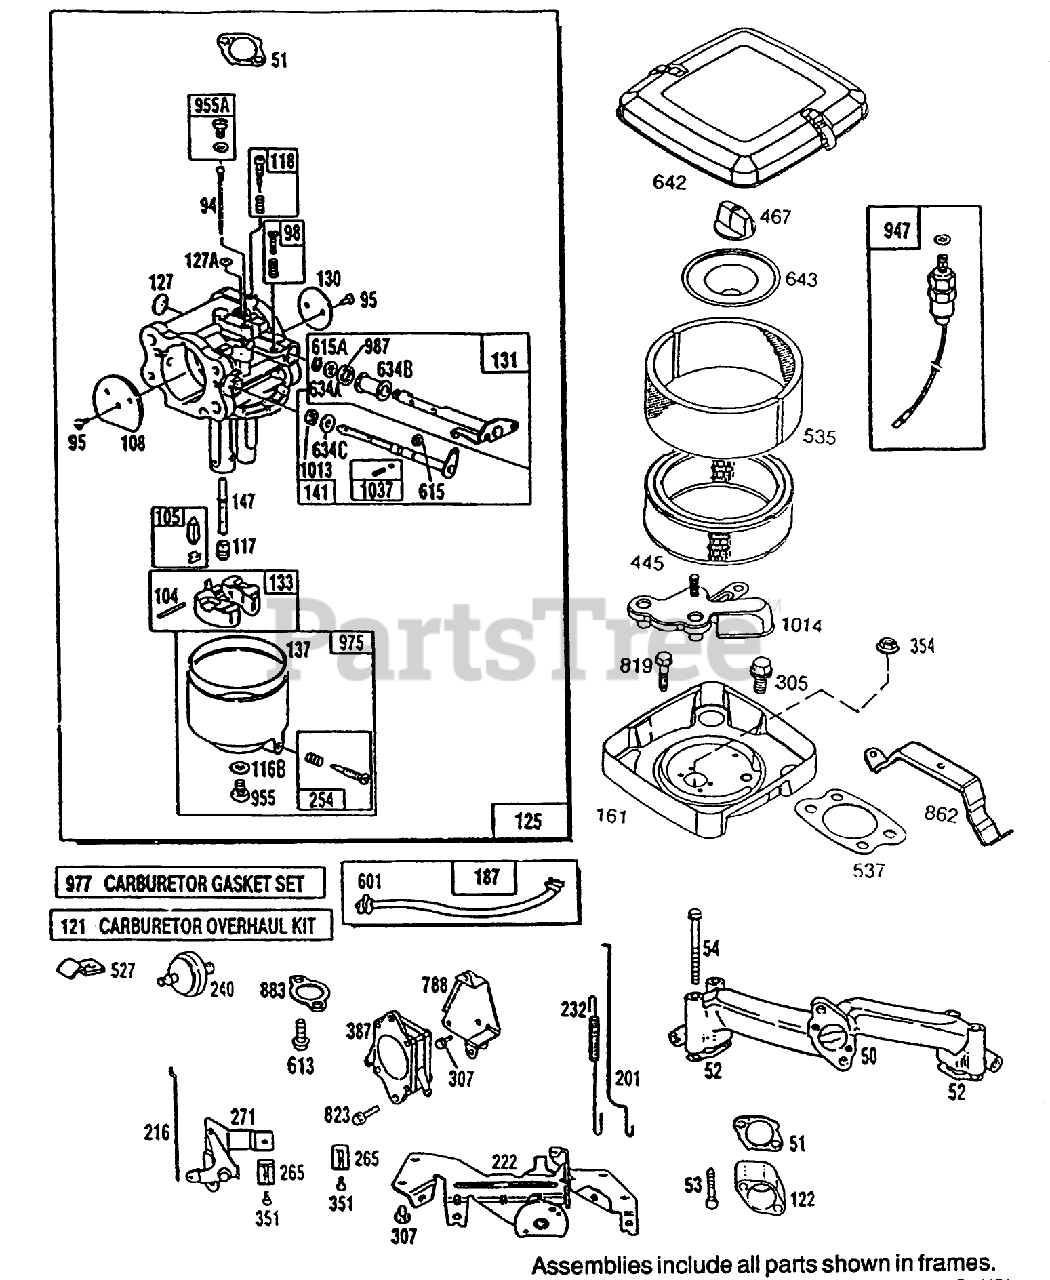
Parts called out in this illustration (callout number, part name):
50	BRIGGS-805409
51	BRIGGS-805149
52	Gasket-Intake Manifold
53	BRIGGS-805360
87	BRIGGS-805054
95	BRIGGS-805561
98	BRIGGS 807705
104	BRIGGS 805586
105	BRIGGS 807706
118	BRIGGS-807707
121	BRIGGS-807962
122	BRIGGS-805329
125	BRIGGS-808255
127	BRIGGS 805570
127A	BRIGGS 805571
131	BRIGGS-807709
133	BRIGGS-807710
137	BRIGGS-807716
141	BRIGGS-807711
147	NOZZLE
161	Base-Air Cleaner
201	BRIGGS 805480
216	BRIGGS-805439
222	BRIGGS-807610
254	BRIGGS-807713
305	BRIGGS 805406
307	BRIGGS-78-4310
351	BRIGGS 805169
445	CARTRIDGE-CLEANER, AIR
467	BRIGGS-491875
535	ELEMENT-FILTER
537	BRIGGS 805655
601	BRIGGS-93053
615	BRIGGS 805578
615A	BRIGGS 805577
634A	BRIGGS 805576
634B	BRIGGS-805574
634C	BRIGGS 805580
643	BRIGGS 805631
819	BRIGGS 805057
823	BRIGGS 805317
955	BRIGGS 805592
955A	BRIGGS-807714
975	BRIGGS-807715
977	BRIGGS 807716
987	BRIGGS 805575
1013	BRIGGS 805581
1037	BRIGGS 807717
